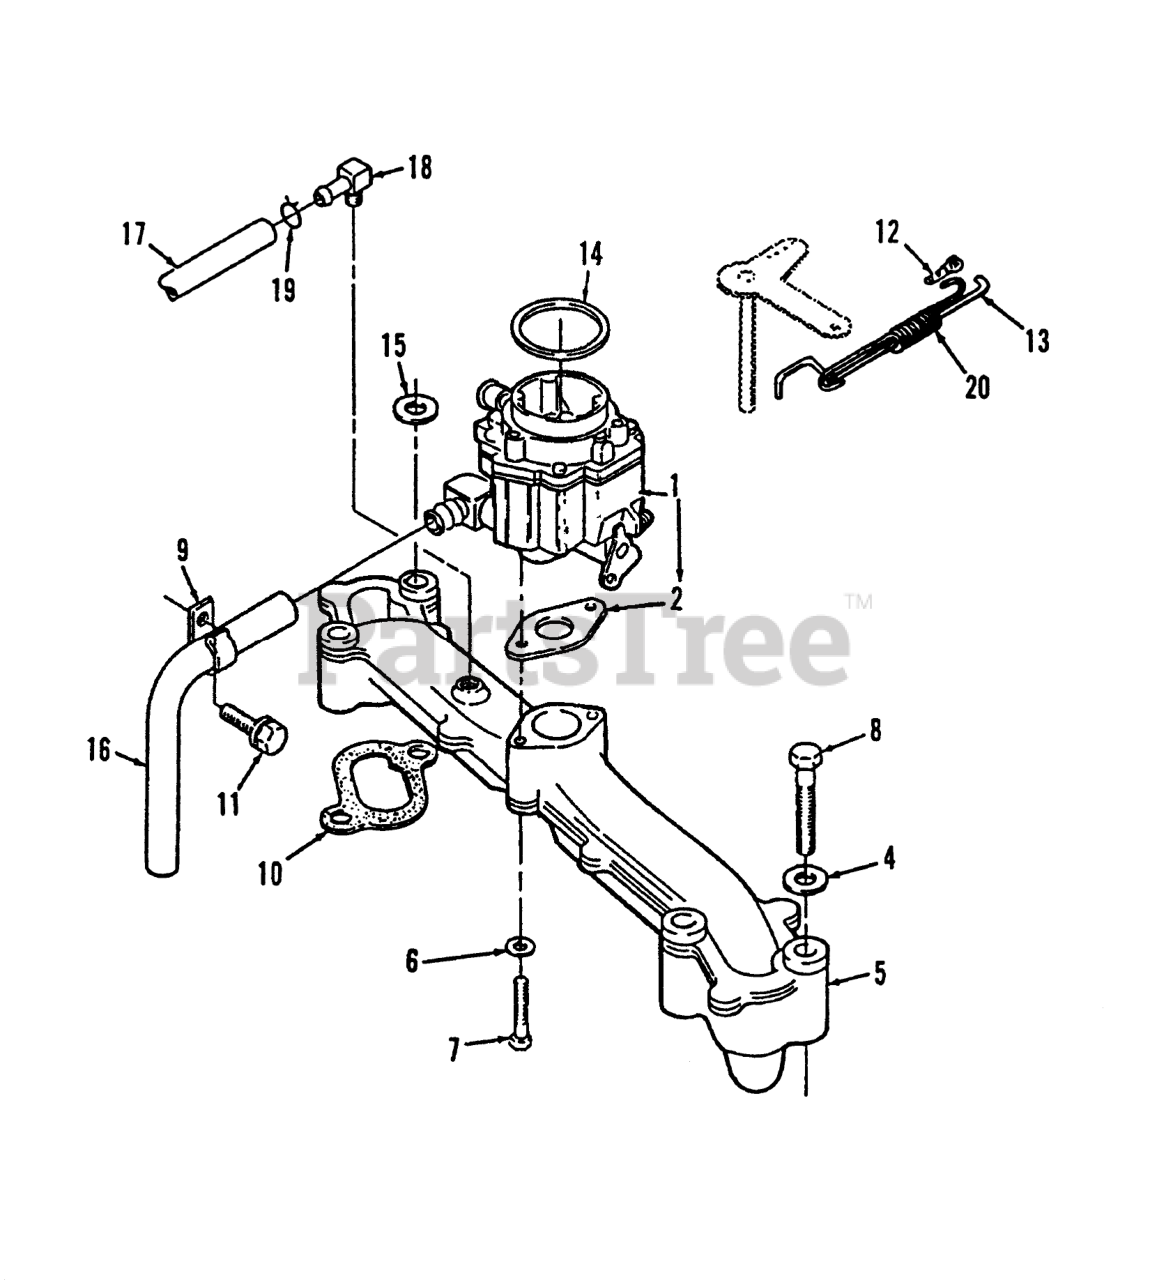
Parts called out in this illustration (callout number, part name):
1	Carburetor (Includes Mounting Gasket, Elbow, & O-Ring)
2	Gasket
4	WASHER-FLAT
5	MANIFOLD
6	Bolt
7	Bolt
9	Clip
10	GASKET
11	Screw
13	GOVERNOR CONTROL ROD
15	FLAT WASHER
16	FIXED-JET
17	HOSE-RUBBER, BREATHER
18	Fitting
19	CLAMP-HOSE, BREATHER
20	Spring-Governor Rod
